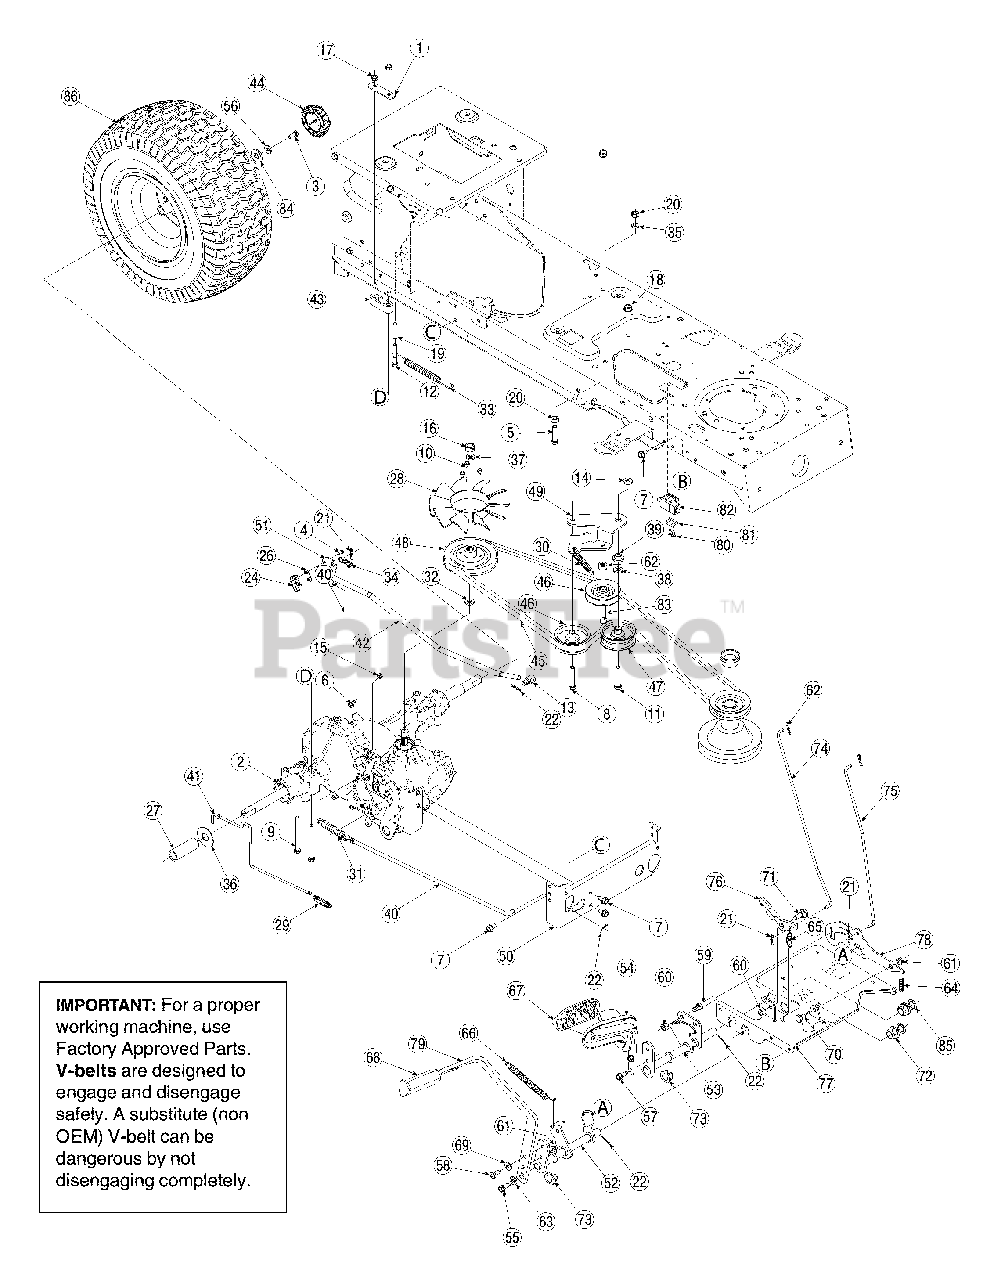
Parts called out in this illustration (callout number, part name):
2	Hydrostatic Transmission
3	Screw, 5/16-24 x.750
4	AB Screw #8-18 x 0.5
5	Hex Bolt 3/8-16 x 1.5
6	TT Screw 1/4-20 x 0.5
7	AB Screw 5/16-12 x 0.75
8	TT Sems Screw 3/8-16 x 1.250
9	Hex Bolt 5/16-18 x 3.5
10	Carriage Screw
11	Hex Bolt 3/8-16 x 2.25
12	Screw, 1/4-20 x 1.250
13	Ferrule
14	Flat Washer,.38 x 1.38 x.125
15	Hex Lock Nut 1/4-20
16	Hex Nut, 1/2-20
17	Flange Lock Nut, 5/16-18
18	Flanged Lock Nut 3/8-16
19	Spacer,.260 x.372 x 1.030 Lg
20	Hex Nut 3/8-16
21	Cotter Pin
22	Cotter Pin
24	Switch
26	Insulator Nut Plate
27	Sleve, 0.758 x 0.821 x 1.5
28	Blade Fan
29	Extension Spring
30	Extension Spring
31	Extension Spring
32	Wire Ring
33	Extension Spring
34	Extension Spring
35	Lock Washer
36	Flat Washer
37	Lock Washer
38	Flat Washer
39	Shoulder Spacer
40	Brake Rod
41	Bypass Rod
42	Control Rod
43	Transaxle Spacer
44	Hub Cap
45	V Belt, A x 78" Lg
46	Idler Pulley
47	Flat Idler Pulley
48	Input Pulley
55	TT Screw 5/16-18 x 0.875
56	Bell Washer,.340 x.872 x.060
57	LD Screw 5/16-18 x 0.75
58	TT Screw 5/16-18 x 0.75
60	Flange Lock Nut, 3/8-16
61	Flange Lock Nut, 5/16-18
62	Spacer,.380ID x.625OD x.21
63	Lock Washer, 5/16
64	Compression Spring
65	Extension Spring
66	Extension Spring
67	Control Pedal
68	Brake Control Pedal
69	Flat Washer
70	Shoulder Screw
71	Shoulder Screw
72	Hex Flange Bearing
73	Hex Flange Bearing
74	Brake Lock Control Rod
75	Cruise Control Rod
76	Cruise Latch
78	Lockout Bracket
81	Switch Plate
82	Interlock Switch
83	Screw, 3/8-16 x 1.500
84	Flat Washer,.350 x 1.59 x.062
85	Flat Washer,.64 x 1.24 x.06
